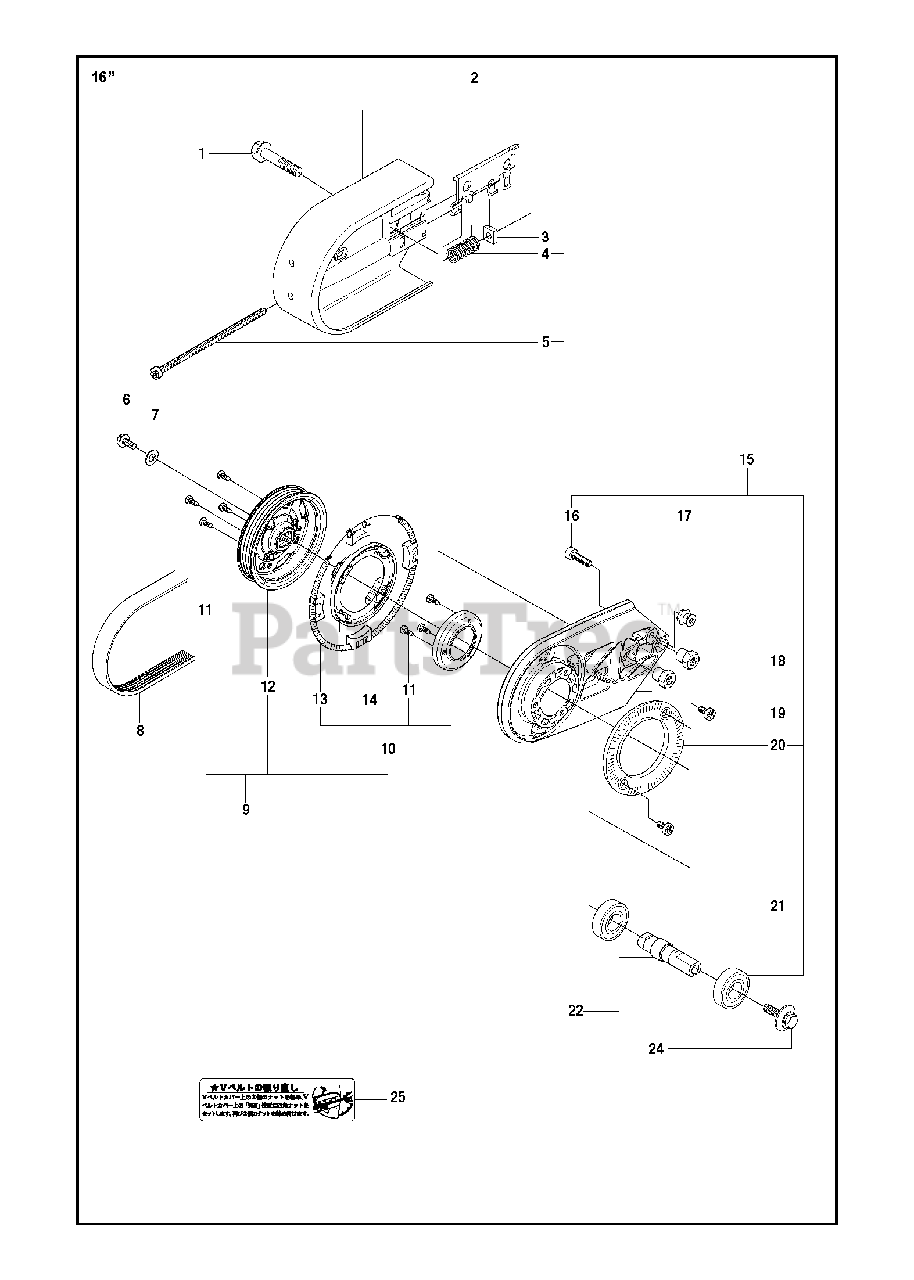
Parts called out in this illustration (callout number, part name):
4	COMPRESSION SPRING
5	SCREW CITXSCM
11	SCREW CCRPANT
16	SCREW ITXSCM
17	TORSION STOP
19	SCREW ITXSCM
21	BALL BEARING
